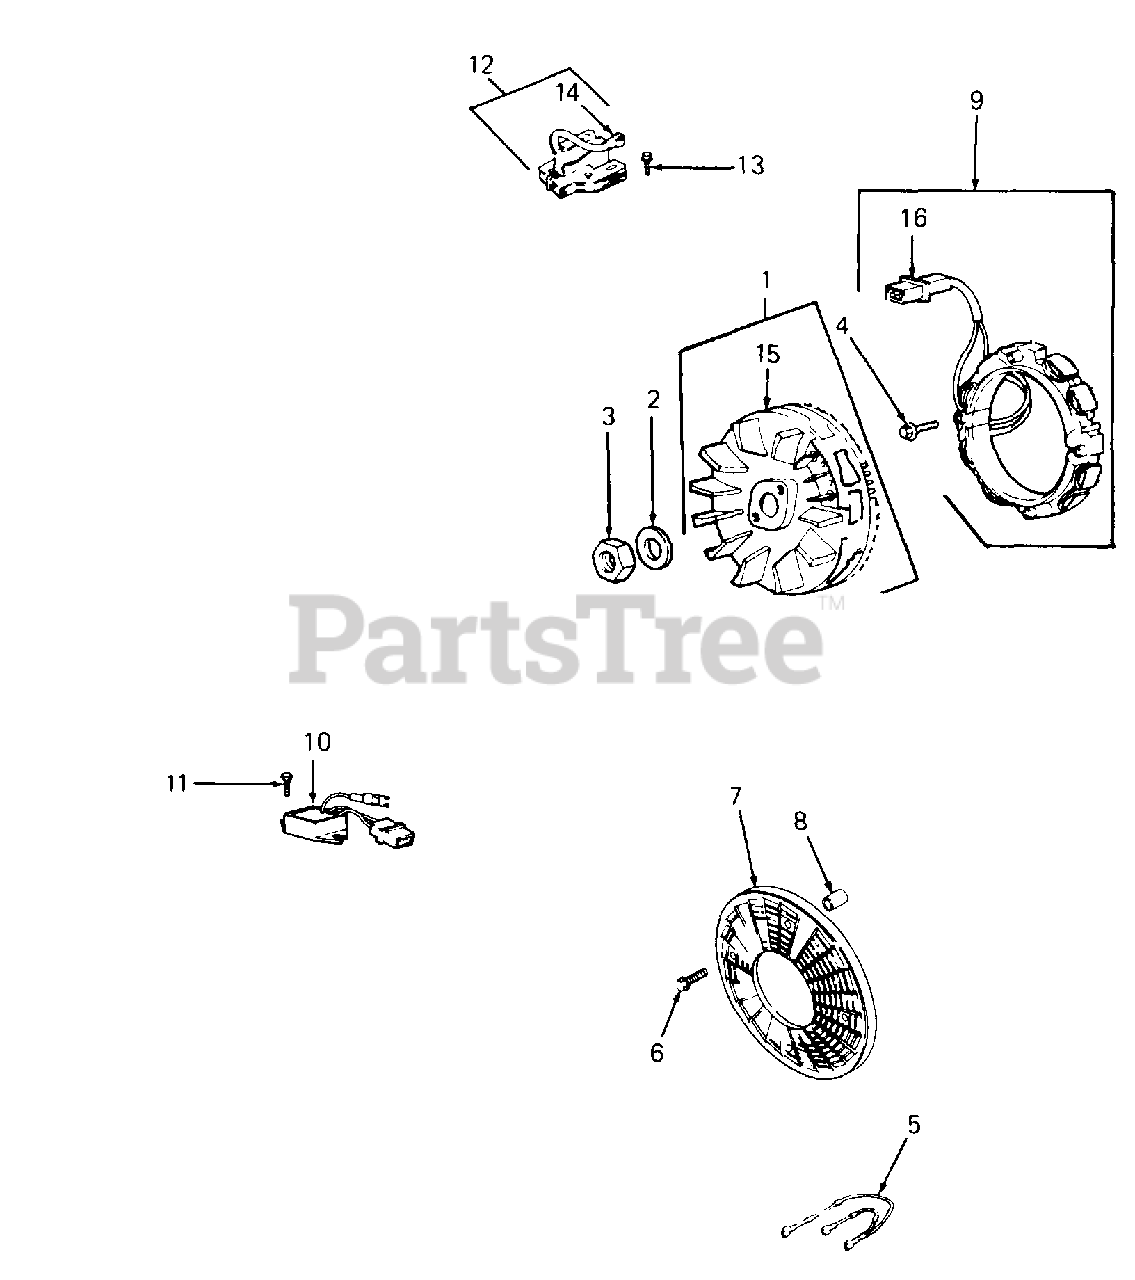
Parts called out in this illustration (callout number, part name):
1	Flywheel & Ring Gear
2	Washer, Spring
4	Screw, Mounting
5	Wire, Ground
6	Screw, Sems
7	Screen, Rotating
8	Spacer
9	Stator, 16 Amp
10	Regulator
11	Screw, Mounting
12	Armature
13	Screw, Mounting
14	Terminal
15	Gear, Flywheel Ring
16	Diode & Connector Assy
